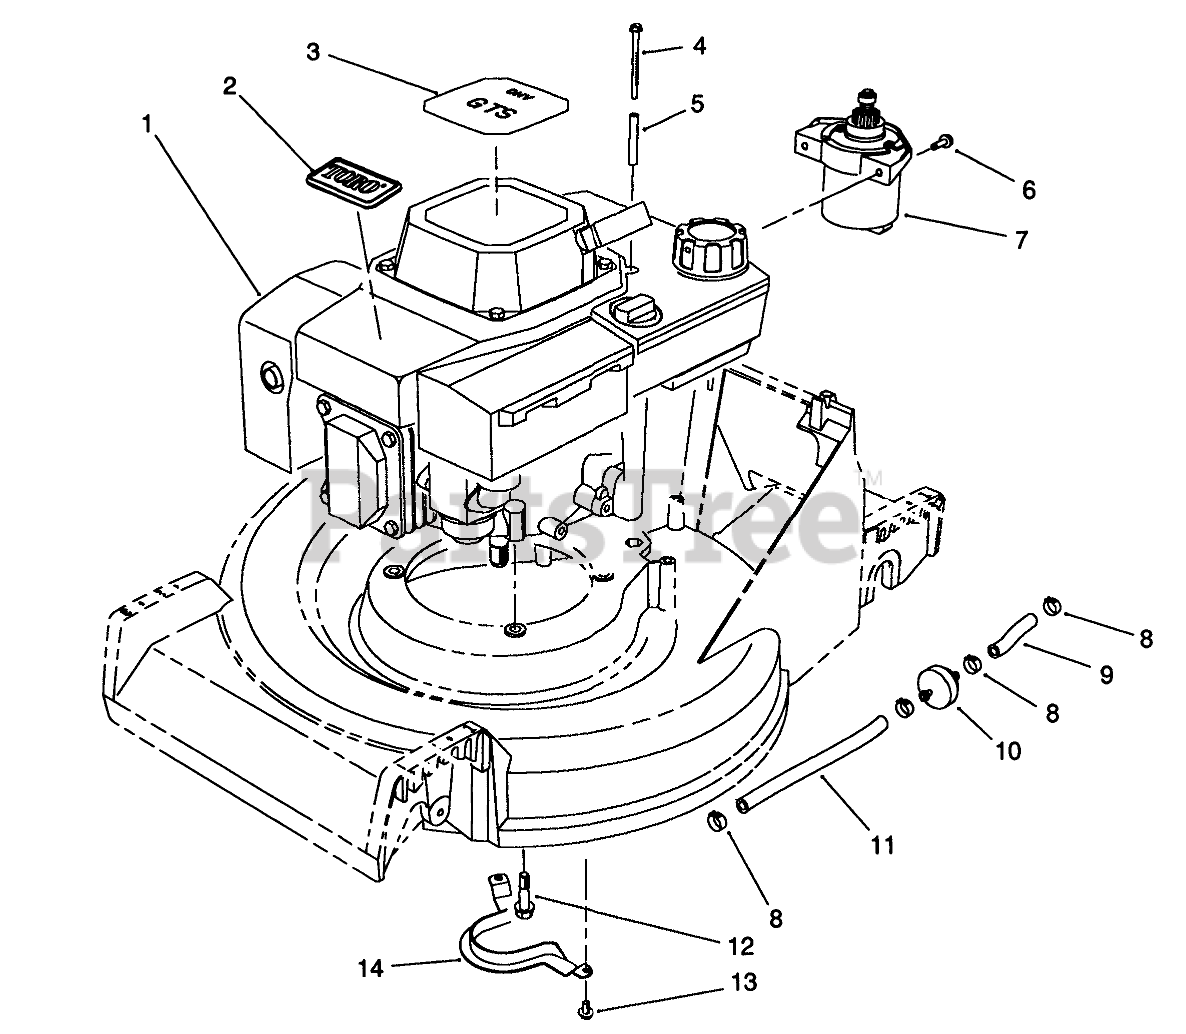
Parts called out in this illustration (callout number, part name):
1	Engine
2	TORO LOGO PLT
3	DECAL - RECOIL GTS
4	THRD FORMING SCREW
5	TUBULAR SPACER
6	SCREW
7	STARTER MOTOR ASM
8	CLAMP-FUEL LINE
9	LINE-GAS
10	FILTER-FUEL
11	HOSE-FUEL
12	SCREW-HWHTF
13	SCREW-HWH
14	BELT GUIDE
